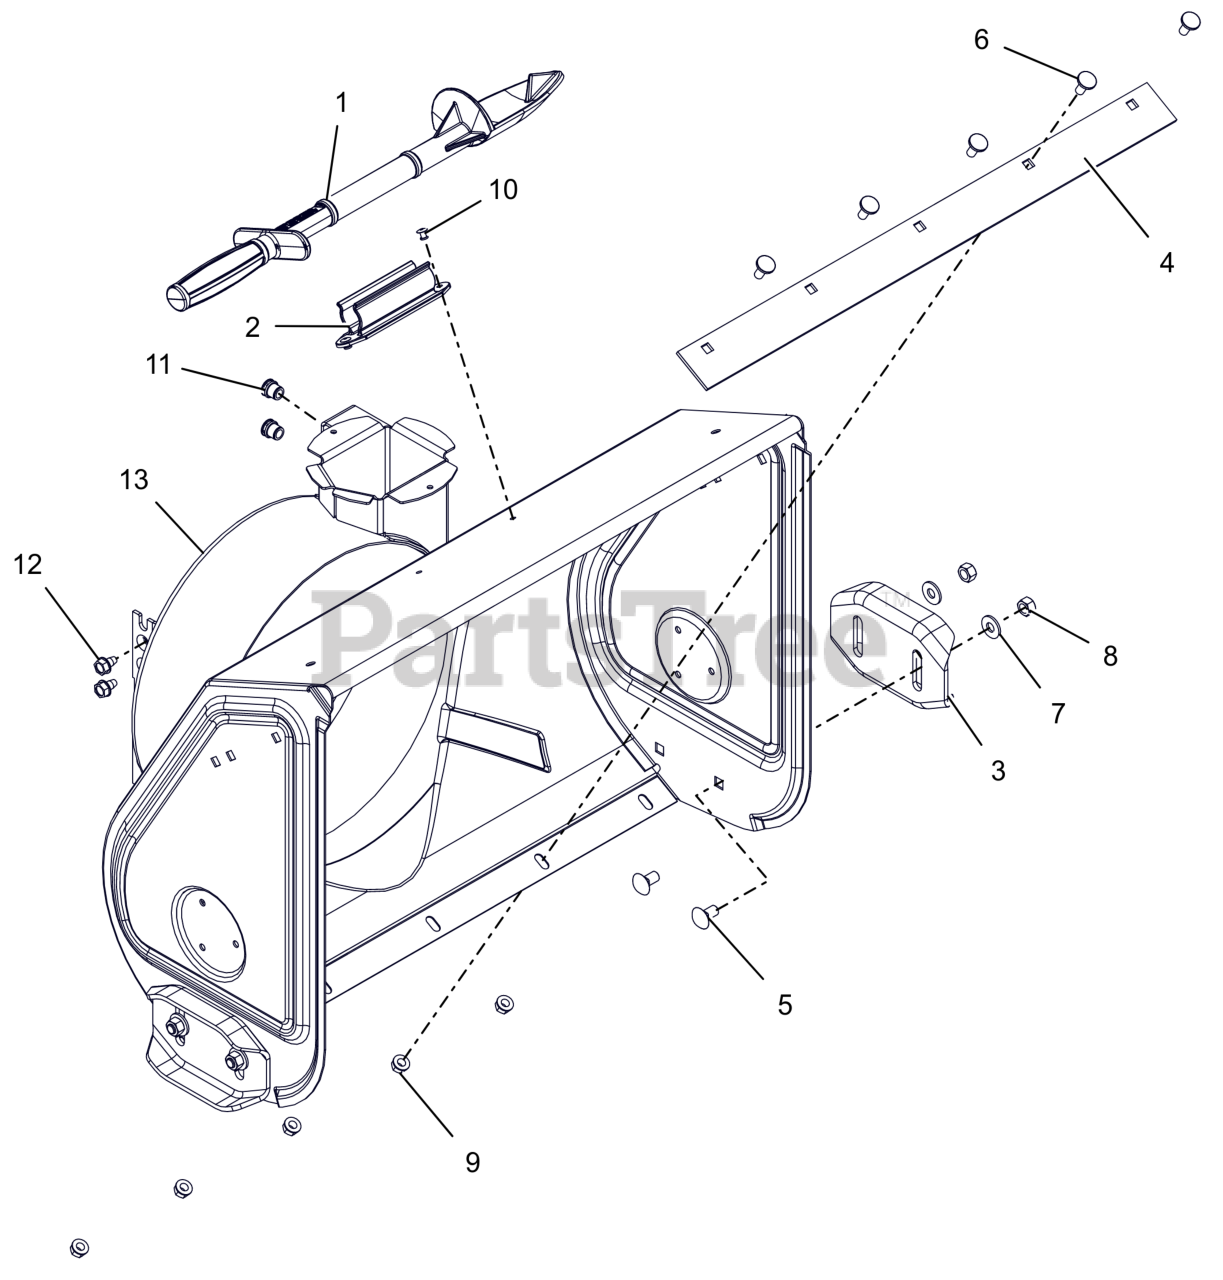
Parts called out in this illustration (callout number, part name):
1	DEVICE, SNOW CLEAN OUT
2	MOUNT, SNOW CLEAN OUT
3	SKID SHOE, REVERSIBLE - ORANGE
4	SCRAPER BLADE, 24" COMPACT HI
5	BLT, RHSSN .38-16X.75 G5 ZCC
6	BOLT, MODIFIED HEAD CARRIAGE
7	WSHR,FLT .375X.875X.083 ZCC
8	NUT-LK-CTR .38-16 ZC120
9	NUT-LK-TOP-FLG .312-18 GF ZCC
10	RVT, POP .1875 ZCC
11	NUT,THD,INSERT .38-16 ZC120
12	SCR,TAP .312-18X.50 HWH TR ZCC
13	BLOWER HOUSING, 24" HI ORANGE
